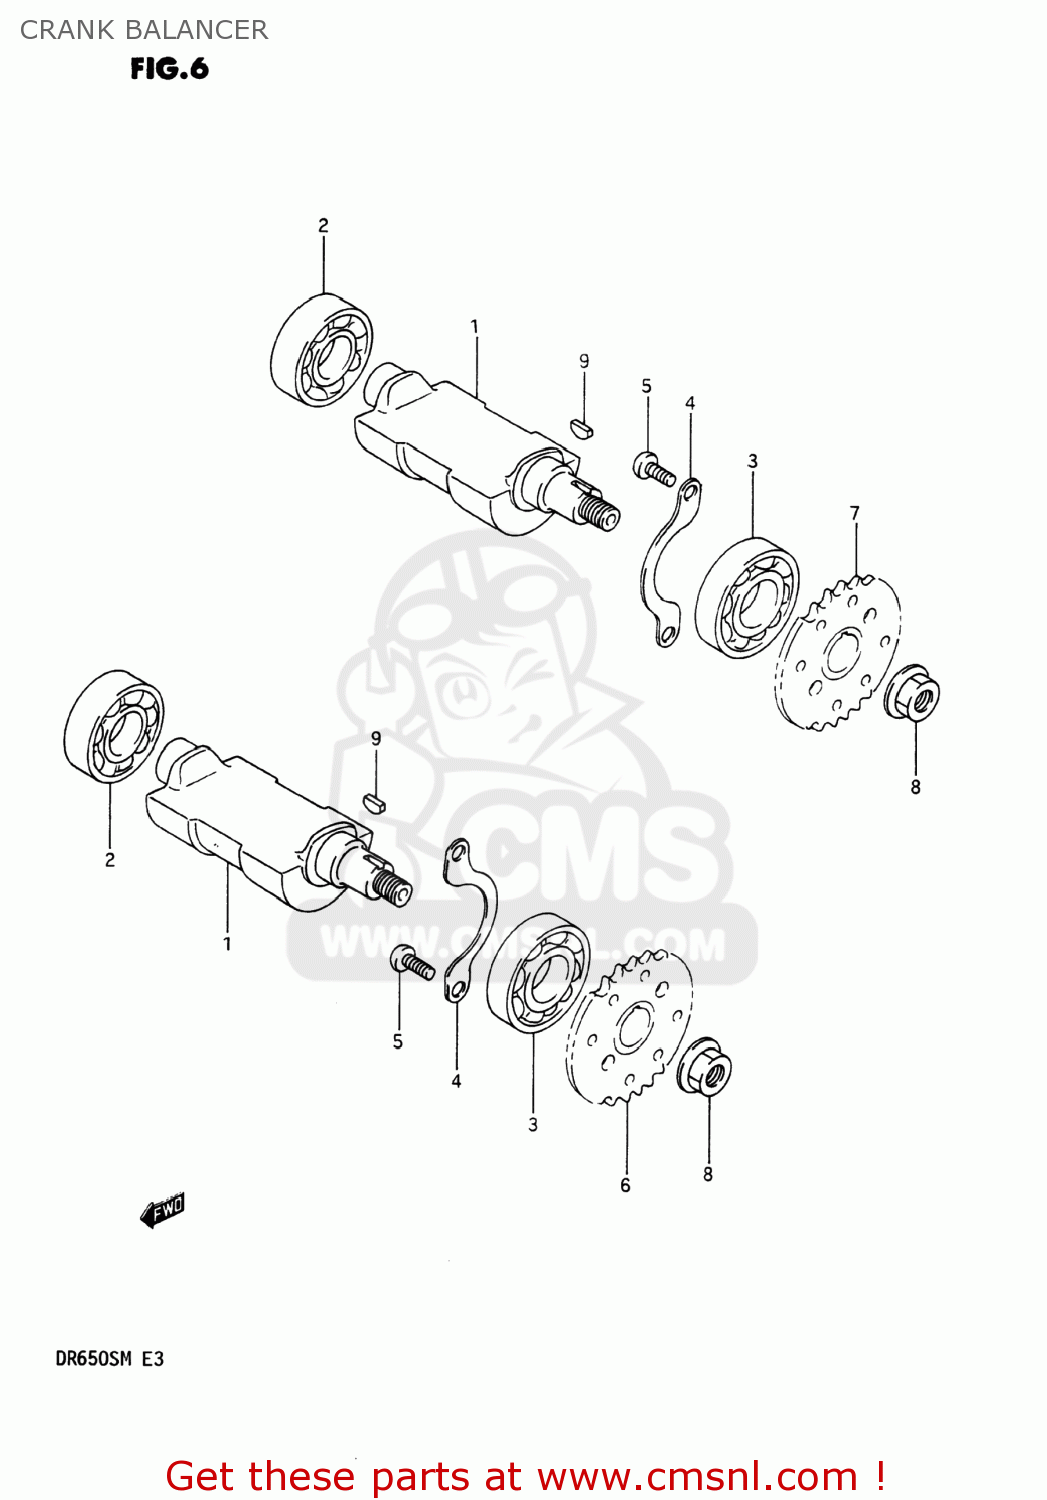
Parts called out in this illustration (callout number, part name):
1	BALANCER,CRANKSHAFT
2	BEARING(20X42X12)
3	BEARING(20X47X12)
4	RETAINER,CRANK BAL BEARING
5	SCREW
6	SPROCKET,BALANCER DRIVE
7	SPROCKET,BALANCER DRIVEN RR
8	NUT
9	KEY
